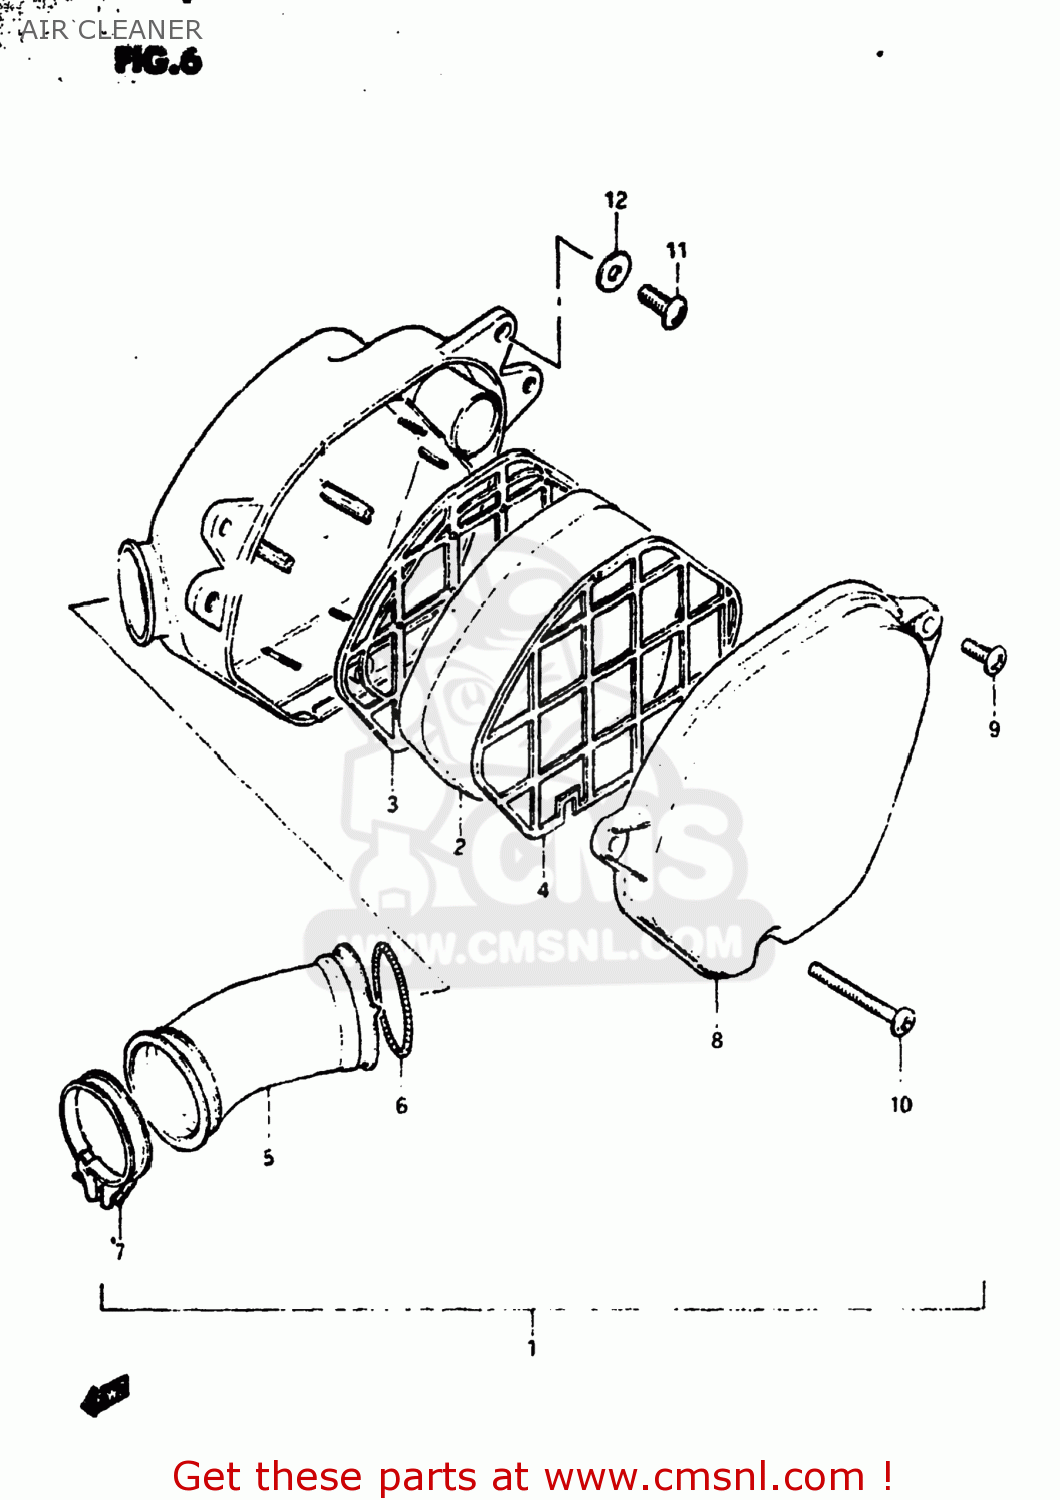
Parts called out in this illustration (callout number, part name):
1	CLEANER ASSY,AIR
2	FILTER
3	HOLDER,FILTER INNER
4	HOLDER,FILTER OUTER
5	TUBE,OUTLET
6	SPRING,AIR CLEANER SIDE
7	CLAMP
8	CAP,CLEANER
9	SCREW
10	SCREW
11	SCREW
12	WASHER
